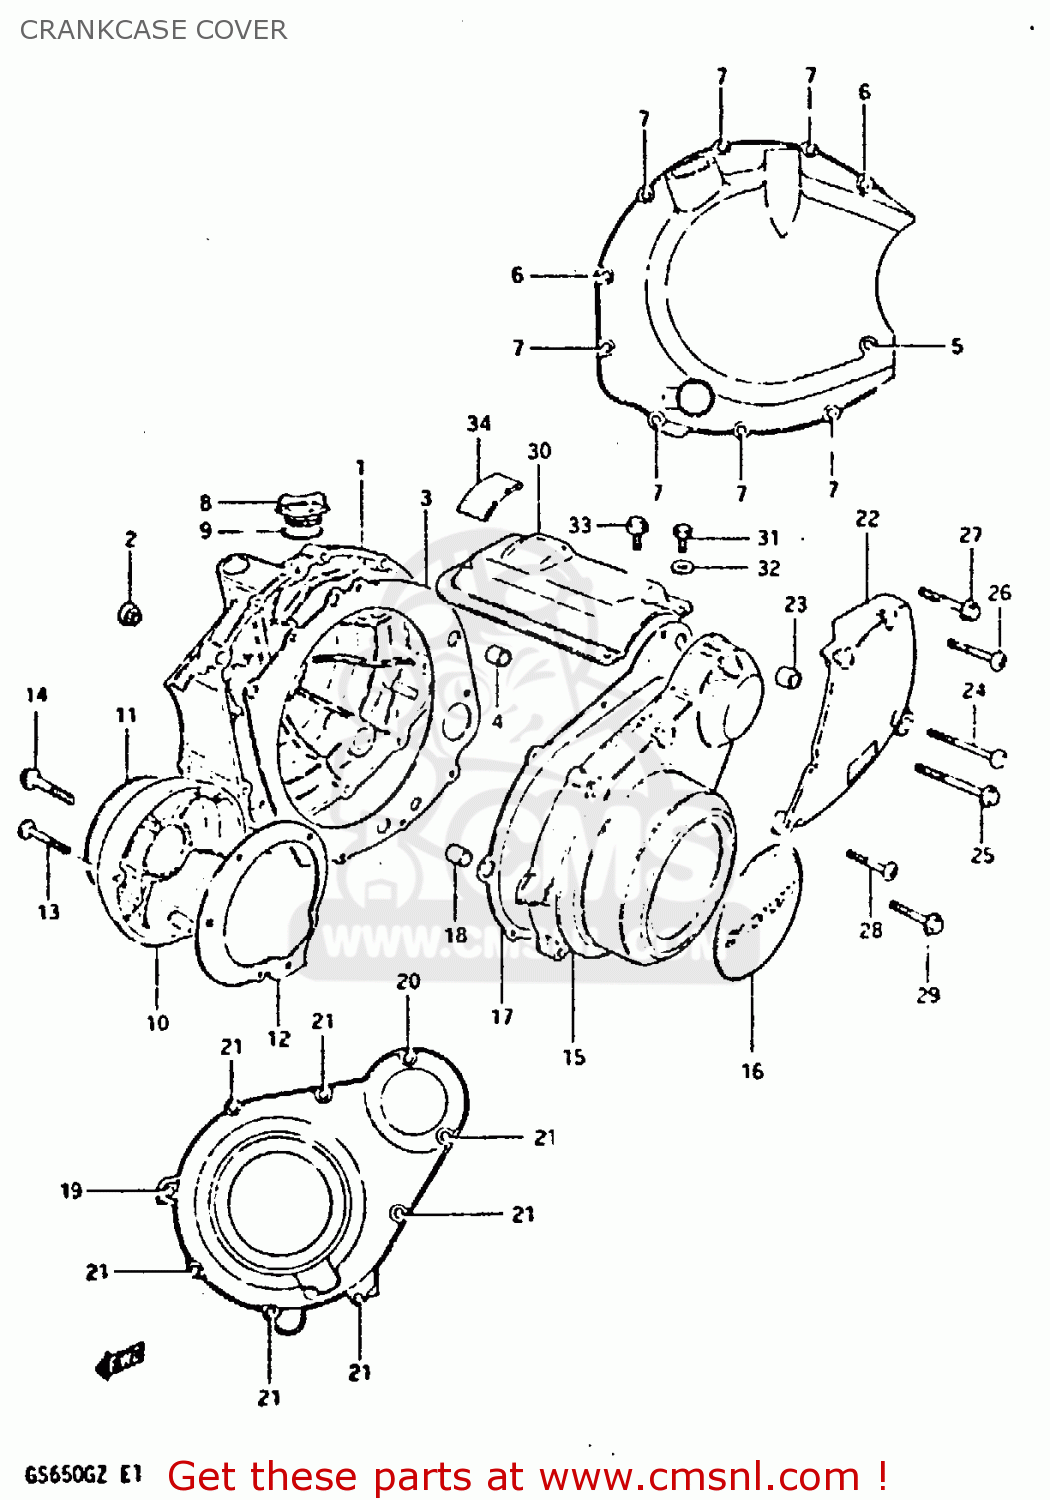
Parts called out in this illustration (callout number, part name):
1	COVER, CLUTCH
2	LENS,OIL LEVEL CHECK
3	GASKET,CLUTCH COVER (MCA)
4	PIN
5	SCREW 6X65
6	SCREW
7	SCREW 6X30
8	PLUG
9	O-RING
10	COVER,CONTACT
11	EMBLEM,CONTACT BREAKER COVER
12	GASKET,CONTACT BREAKER COVER (NAS)
13	SCREW
14	BOLT (5*30)
15	COVER, GENERATOR
16	EMBLEM,MAGNETO COVER
17	GASKET,MAGNETO COVER (MCA)
18	PIN
19	BOLT
20	BOLT (6X35)
21	SCREW 6X30
22	COVER, SECONDARY DRIVE UNIT
23	PIN
24	SCREW
25	BOLT (6X40)
26	SCREW 6X30
27	BOLT (6X30)
28	SCREW
29	BOLT
30	COVER
31	BOLT 5X16
32	WASHER
33	BOLT (5*8)
34	DAMPER,STARTER MOTOR CLUTCH
